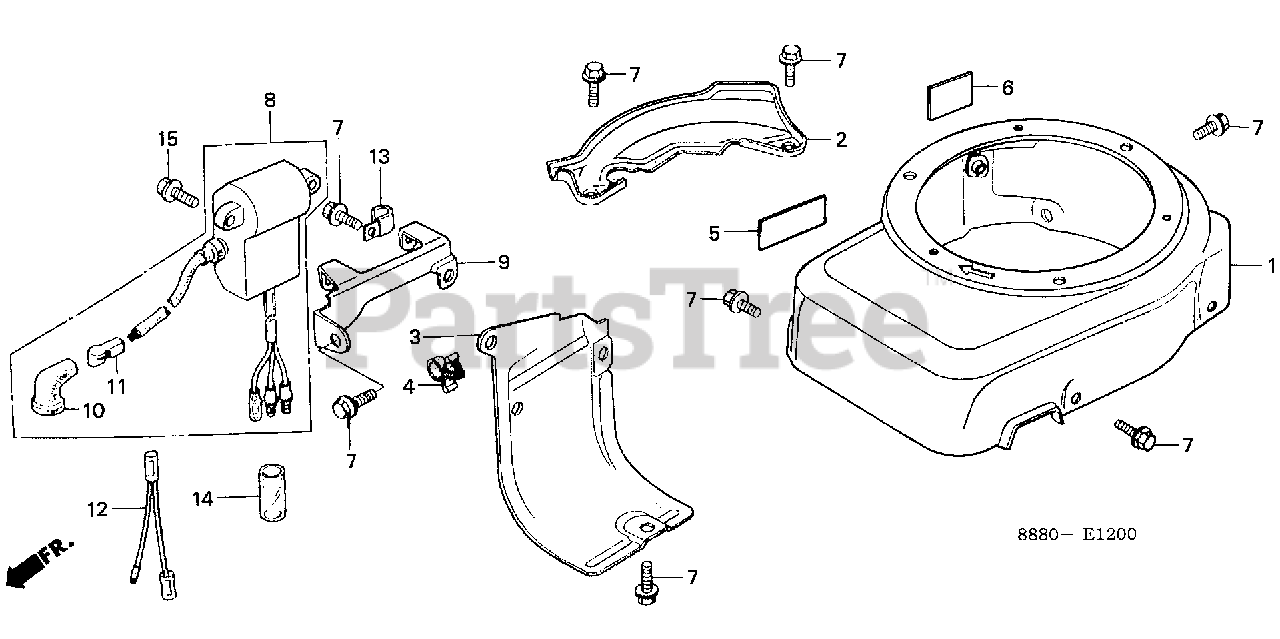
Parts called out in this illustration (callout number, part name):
1	COVER, FAN *NH67* (SPARKLE WHITE)
2	PLATE, SIDE
4	CLIP, IGNITION WIRE (8MM)
6	MARK, OIL CAUTION
7	BOLT, FLANGE (6X12) (CT200)
